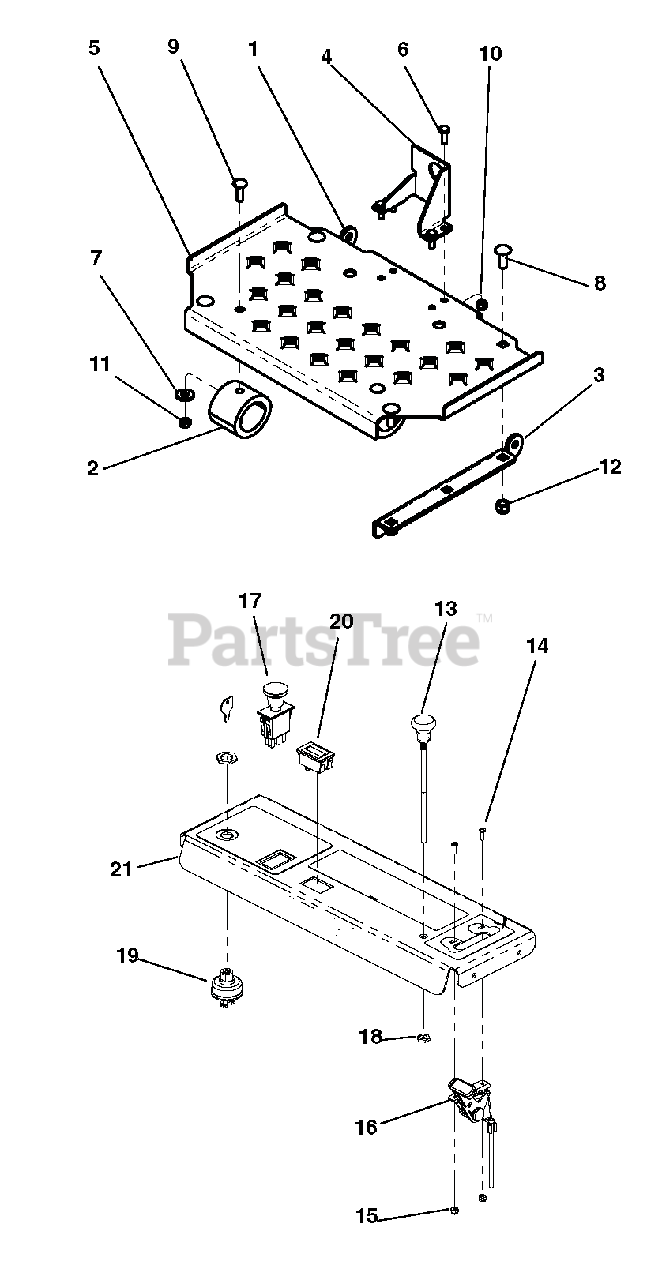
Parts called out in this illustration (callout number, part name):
1	PLATE, PLATFORM TAB
2	BUMPER, MINER GBR-6
3	PLATE, PLATFORM TAB LH
4	ANCHOR, OPC
5	PLATFORM
6	BOLT, 1/4-20X.750 HEX 5 Y
7	WASHER, .313 REG FLAT Y
8	BOLT, 3/8-16X1.00 CRG 5 SN Y
9	BOLT, 5/16-18X1.00 CRG 2 Y
10	LOCKNUT, 1/4-20 NYLOC Y
11	LOCKNUT, 5/16-18 NYLOC Y
12	LOCKNUT, 3/8-16 NYLOC Y
13	CABLE, CHOKE 31.0"
14	SCREW,8-32X1/2
15	#8.32 ELASTIC STOP NUT
16	CABLE, THROTLE 48.0"
17	SWITCH, PTO ENGAGEMENT
18	NUT, 3/8 UNF HEX GR 5 ZN
19	SWITCH, KEY - 3 POSITION
20	METER, HOUR - LCD ALT. (ENM)
21	CONTROL PANEL W/DECALS GDANE
